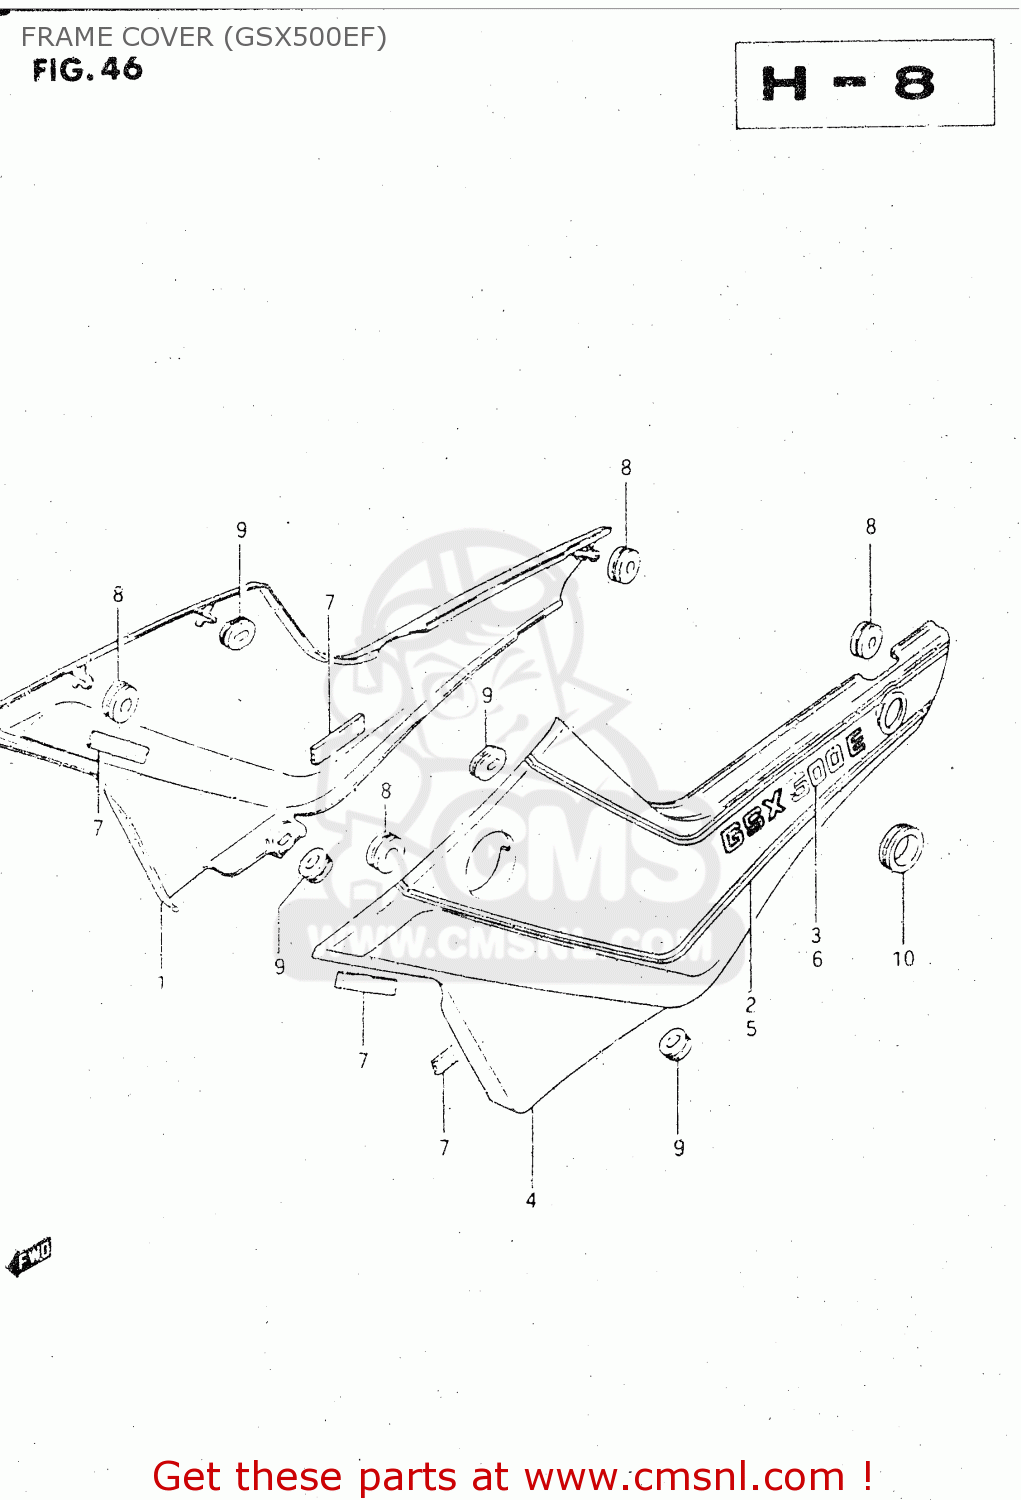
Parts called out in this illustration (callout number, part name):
1	COVER, FRAME RH
2	TAPE SET,FRAME COVER,RIGHT
3	EMBLEM
4	COVER, FRAME LH
5	TAPE SET,FRAME COVER
6	EMBLEM
7	RUBBER,FRAME COVER
8	CUSHION
9	CUSHION
10	GROMMET,SEAT LOCK HOLE
